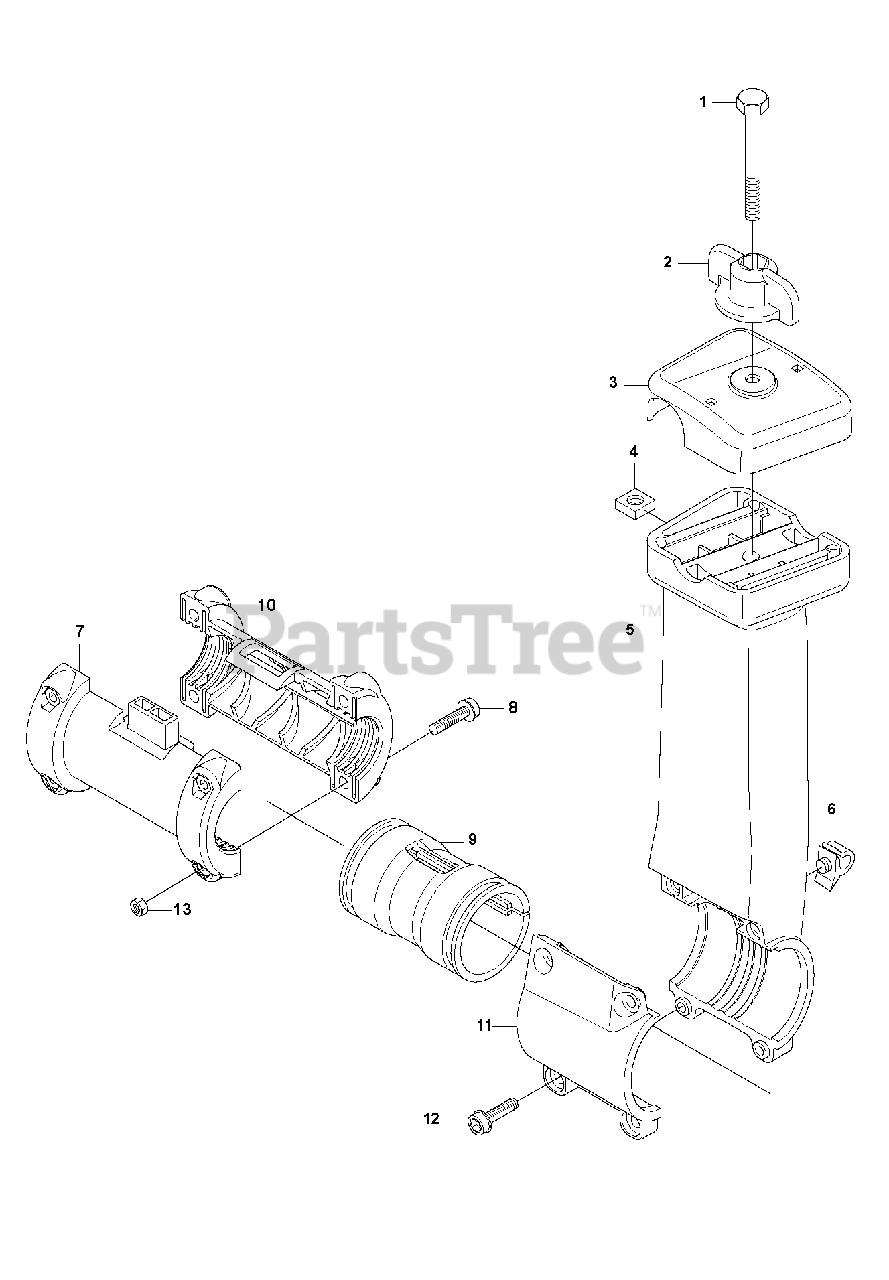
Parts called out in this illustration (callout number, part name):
7	CLAMPING SLEEVE
9	VIBRATIONS ABSORBER
10	CLAMPING SLEEVE ASSY
12	SCREW
